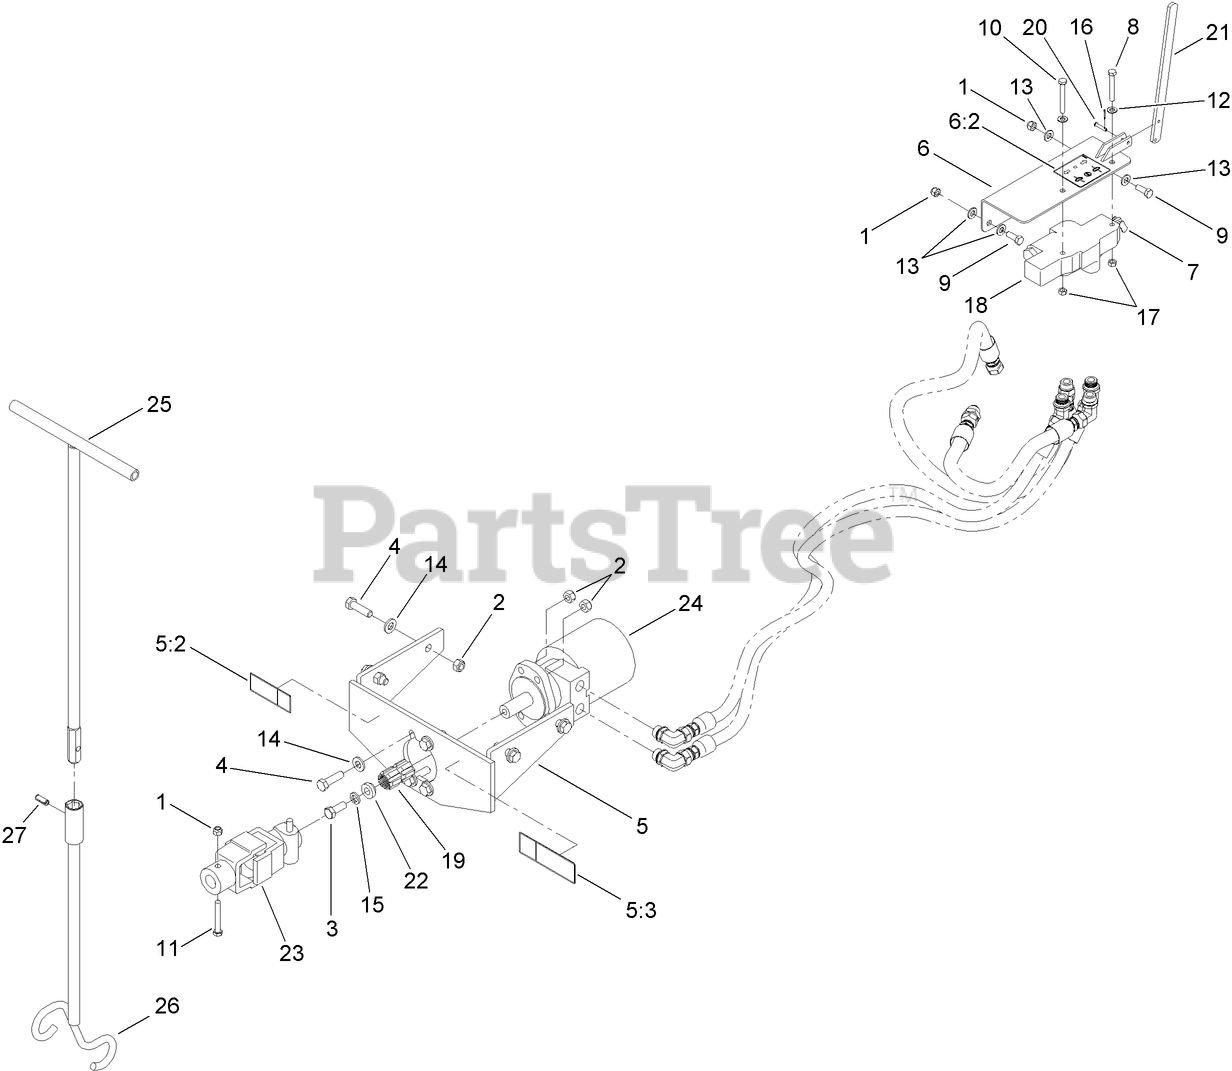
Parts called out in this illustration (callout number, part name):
1	NUT-HEX
2	LOCKNUT
3	SCREW-HH
4	SCREW-HH
5	MOUNT ASM
5:2	DECAL-DANGER
5:3	DECAL-DANGER, ENTANGLEMENT
6	BRACKET ASM
6:2	DECAL-HYDRABORE DIRECTION
7	LINK-#50, CONNECT (SINGLE PITCH)
8	SCREW-HH
9	SCREW-HH
11	SCREW-HH
12	WASHER-FLAT
13	WASHER-FLAT
14	WASHER-FLAT
15	WASHER-LOCK
16	PIN-COTTER
17	NUT-LOCK, CONE
18	SINGLE SPOOL VALVE ASM
19	ADAPTER
20	PIN-CLEVIS
21	LEVER-VALVE
22	RETAINER-ADAPTER
23	U-JOINT ASM
24	HYD MOTOR ASM
25	HANDLE-TOOL, GUIDE
26	TOOL-GUIDE, ROD
27	PIN-ROLL
